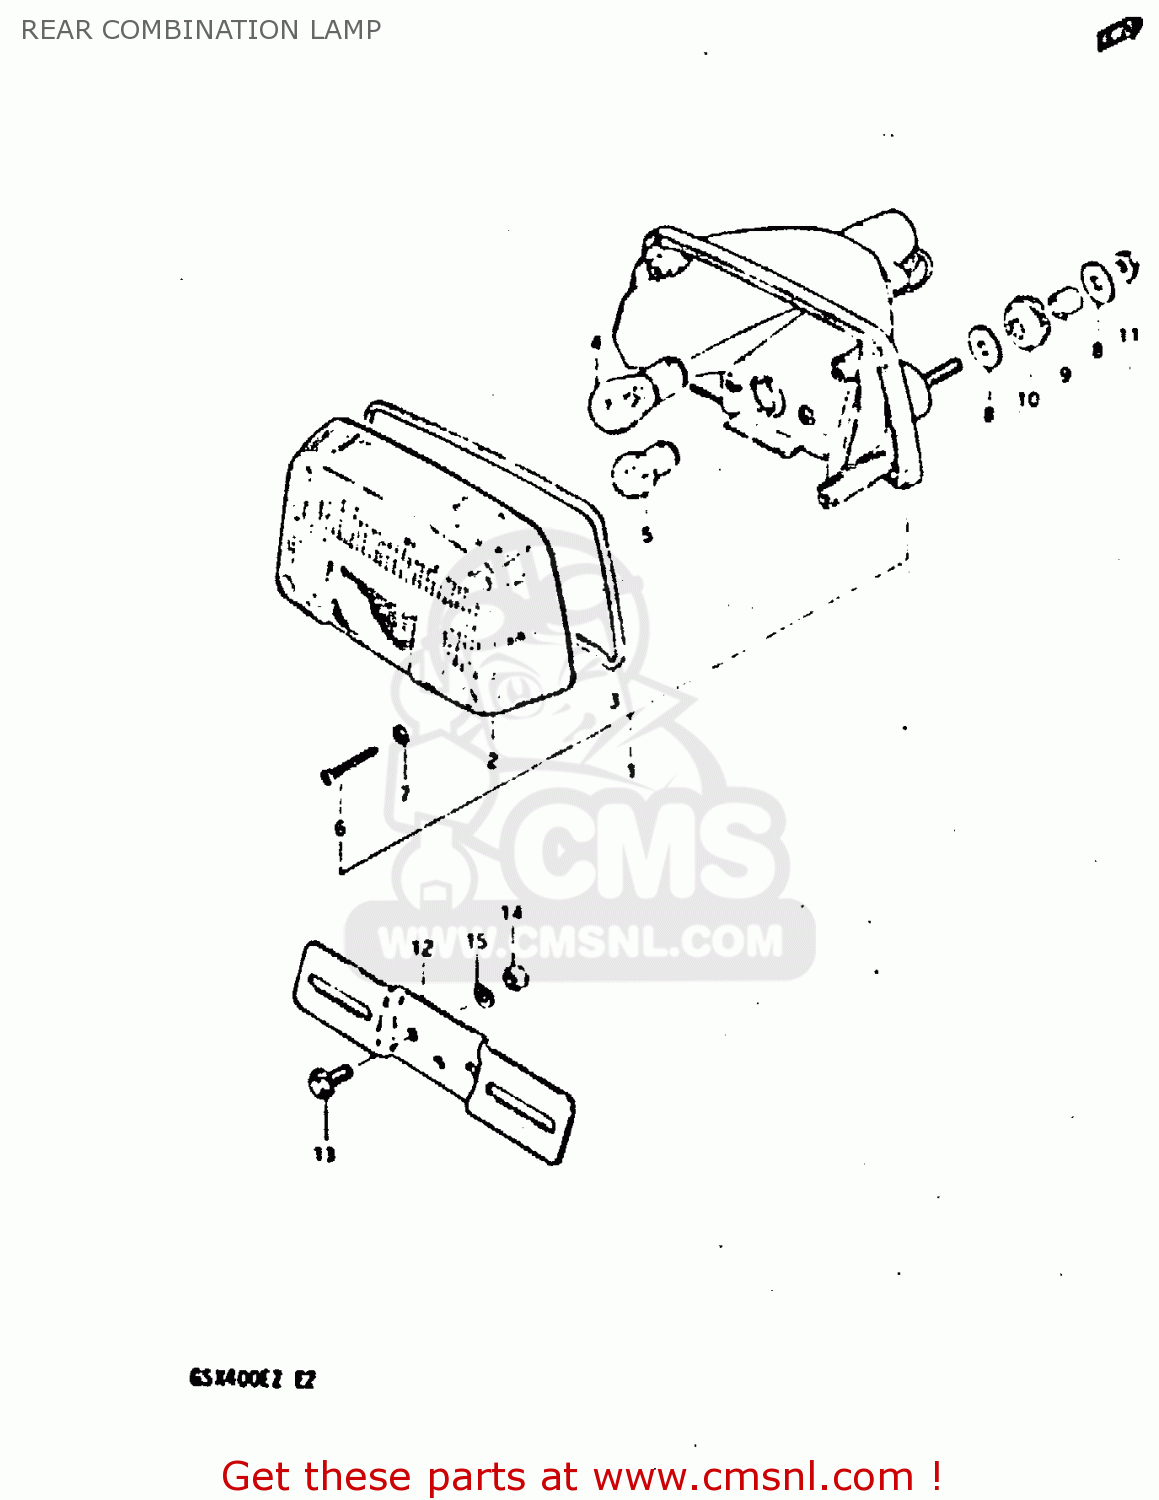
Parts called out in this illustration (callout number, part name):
1	LAMP ASSY, REAR COMBINATION
2	LENS,REAR COMBINATION LAMP
3	GASKET
4	BULB(12V21/5W)
5	BULB
6	SCREW
7	GASKET (NAS)
8	WASHER
9	SPACER (6.8X10X11.5)
10	CUSHION
11	NUT 6MM
12	BRACKET, LICENSE PLATE
13	BOLT
14	NUT
15	LOCK WASHER
